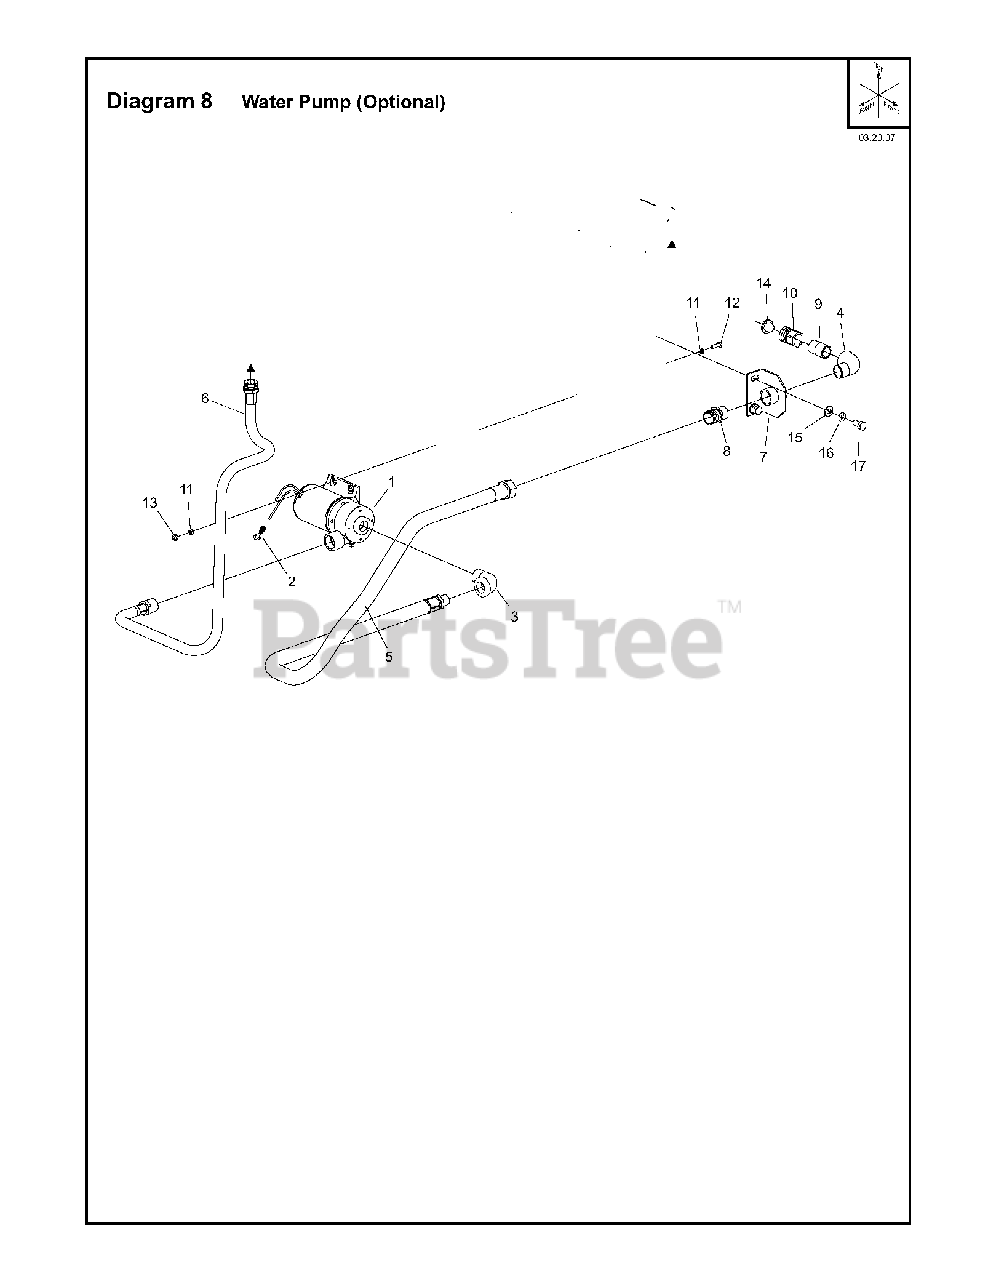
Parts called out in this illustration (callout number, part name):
2	TERMINAL. RING 1/4" (14-18GA)
5	HOSE ASSY
6	HOSE ASSY
7	WATER PUMP BRACKET - PTD BLK
11	WASHER
12	HHCS. M6 x 1.0 x 25 DIN931 Z/P
13	LOCKNUT. FIBER M6 DIN 985
16	LOCKWASHER. SPLIT M10
17	HHCS. M10 x 1.5 x 20 DIN933 ZP
